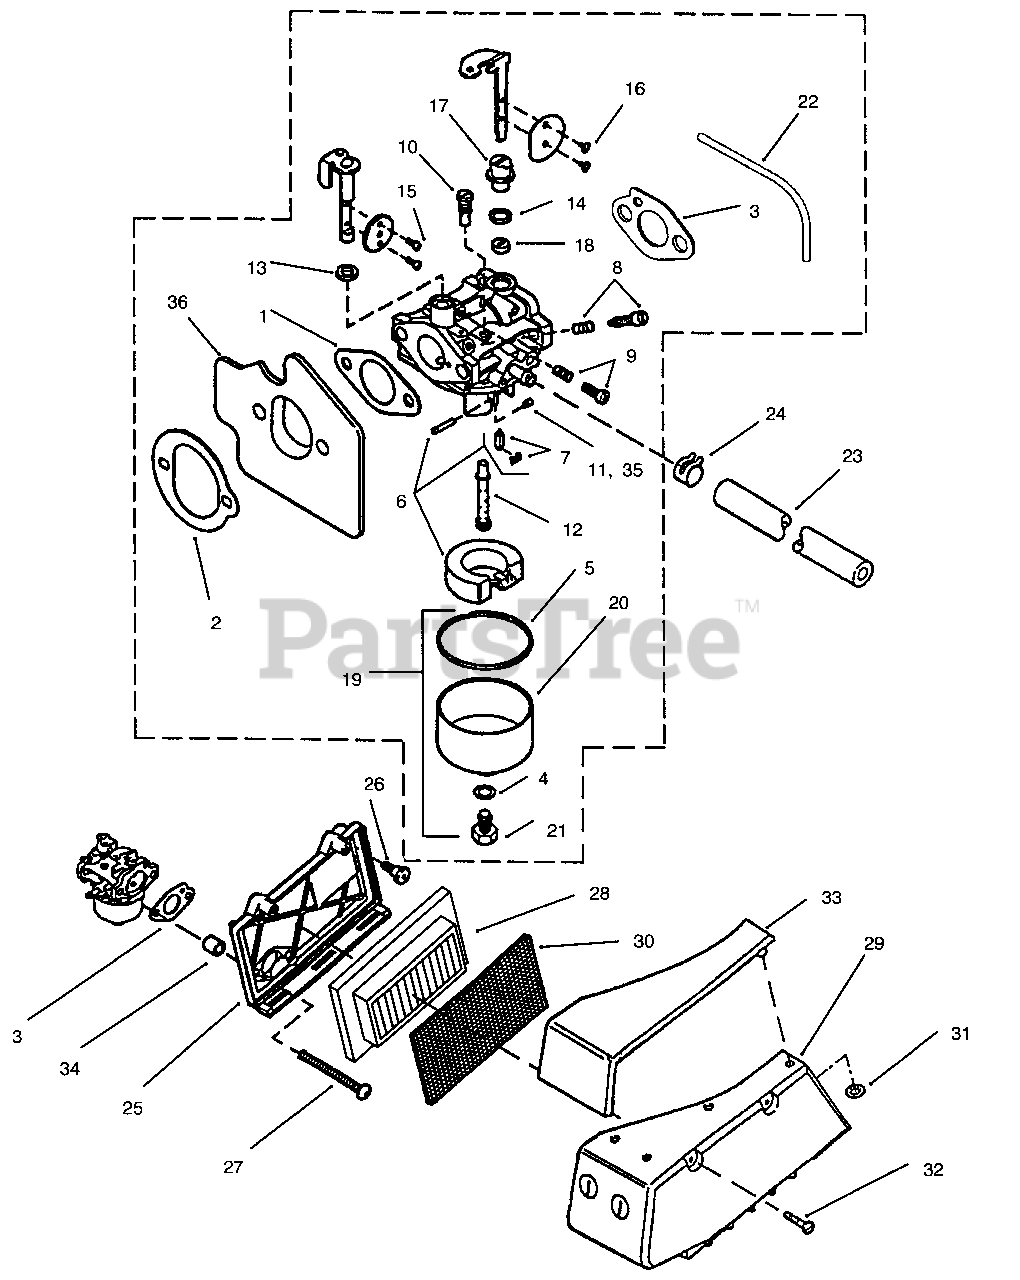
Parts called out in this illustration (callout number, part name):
1	Gasket-Carb. to Spacer
2	Gasket-Spacer to Engine
3	Gasket-Air Filter Base
4	Gasket-Bowl Retainer
5	Gasket-Fuel Bowl
6	Kit-Float & Needle (Incl. Ref. No. 7)
7	Needle and Clip
8	Kit-Idle Needle & Spring
9	Kit-Idle Speed
10	Pilot Jet
11	Main Jet
13	Seal-Throttle Shaft
14	Seal-Choke Shaft
15	Screw-Throttle Valve
16	Screw-Choke Valve
17	Pivot-Upper Choke Shaft
18	Pivot-Lower Choke Shaft
19	Kit-Bowl (Incl. Ref. No. 4,5,20,21)
20	Bowl-Fuel
21	Screw-Bowl Retainer
22	Hose-Carb Vent
23	Gas Line
24	Clamp-Hose
25	Base-Air Filter
27	Screw-Carb. to Engine
28	Filter-Air
29	Assembly-Cover,Air Filter (Incl. Ref. No. 30-33)
30	Pre-Filter
31	Pushnut
33	Cover-AirBox
35	Main Jet-High Altitude (Over 3500 feet)
36	Assy-Spacer & Oil Nozzle
